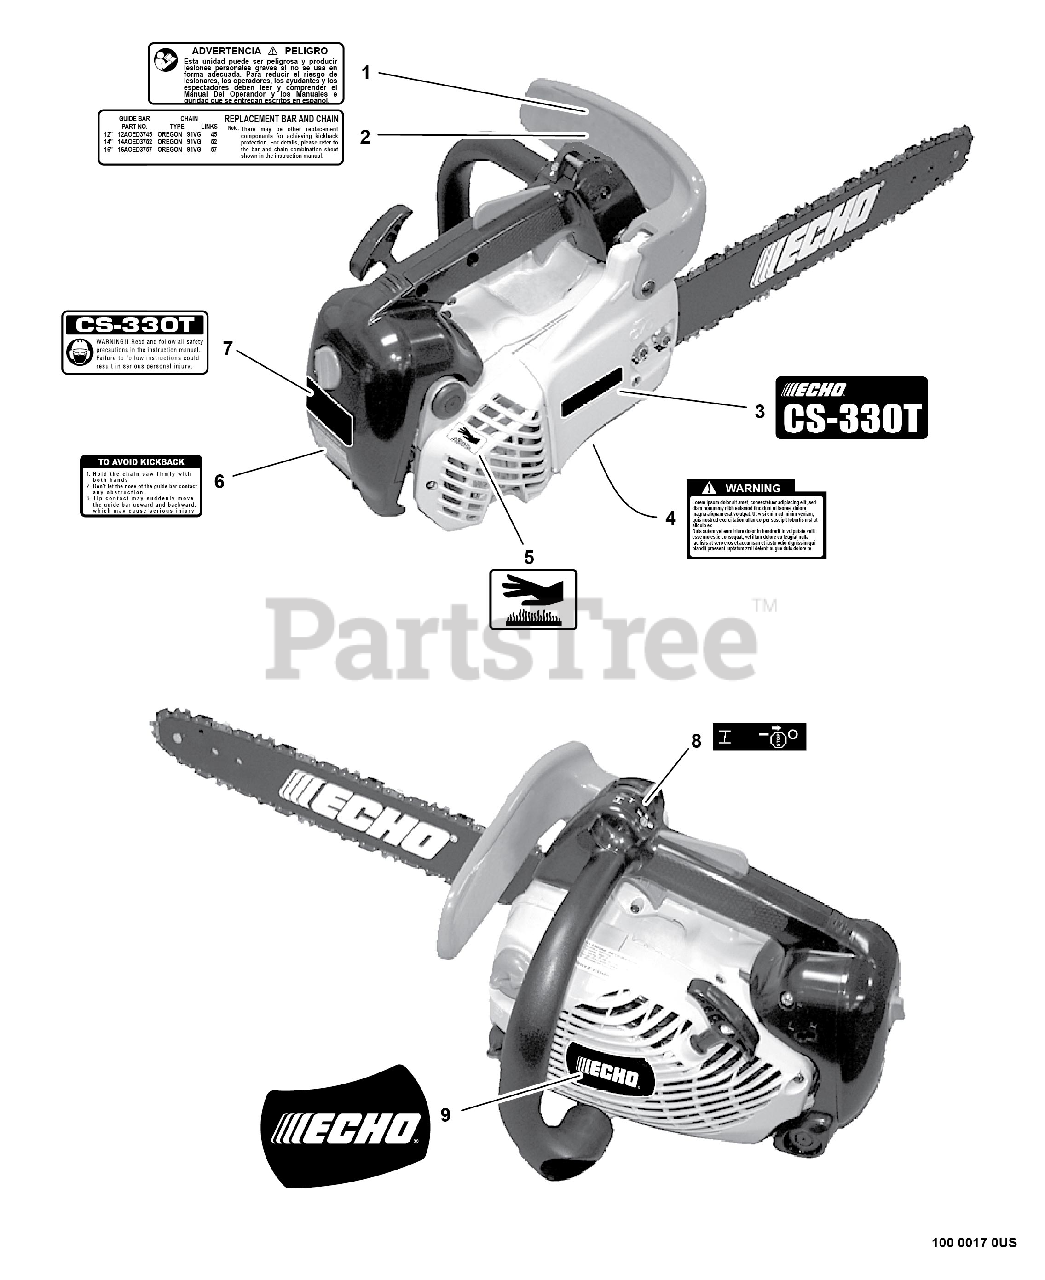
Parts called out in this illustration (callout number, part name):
1	LABEL - CAUTION -- SPANISH
2	LABEL - BAR & CHAIN
3	LABEL - MODEL CS-330T
4	LABEL - WARNING
5	LABEL - HOT SURFACE
6	LABEL - KICK BACK
7	LABEL - MODEL CS-330T
8	LABEL - STOP
9	LABEL - ECHO
